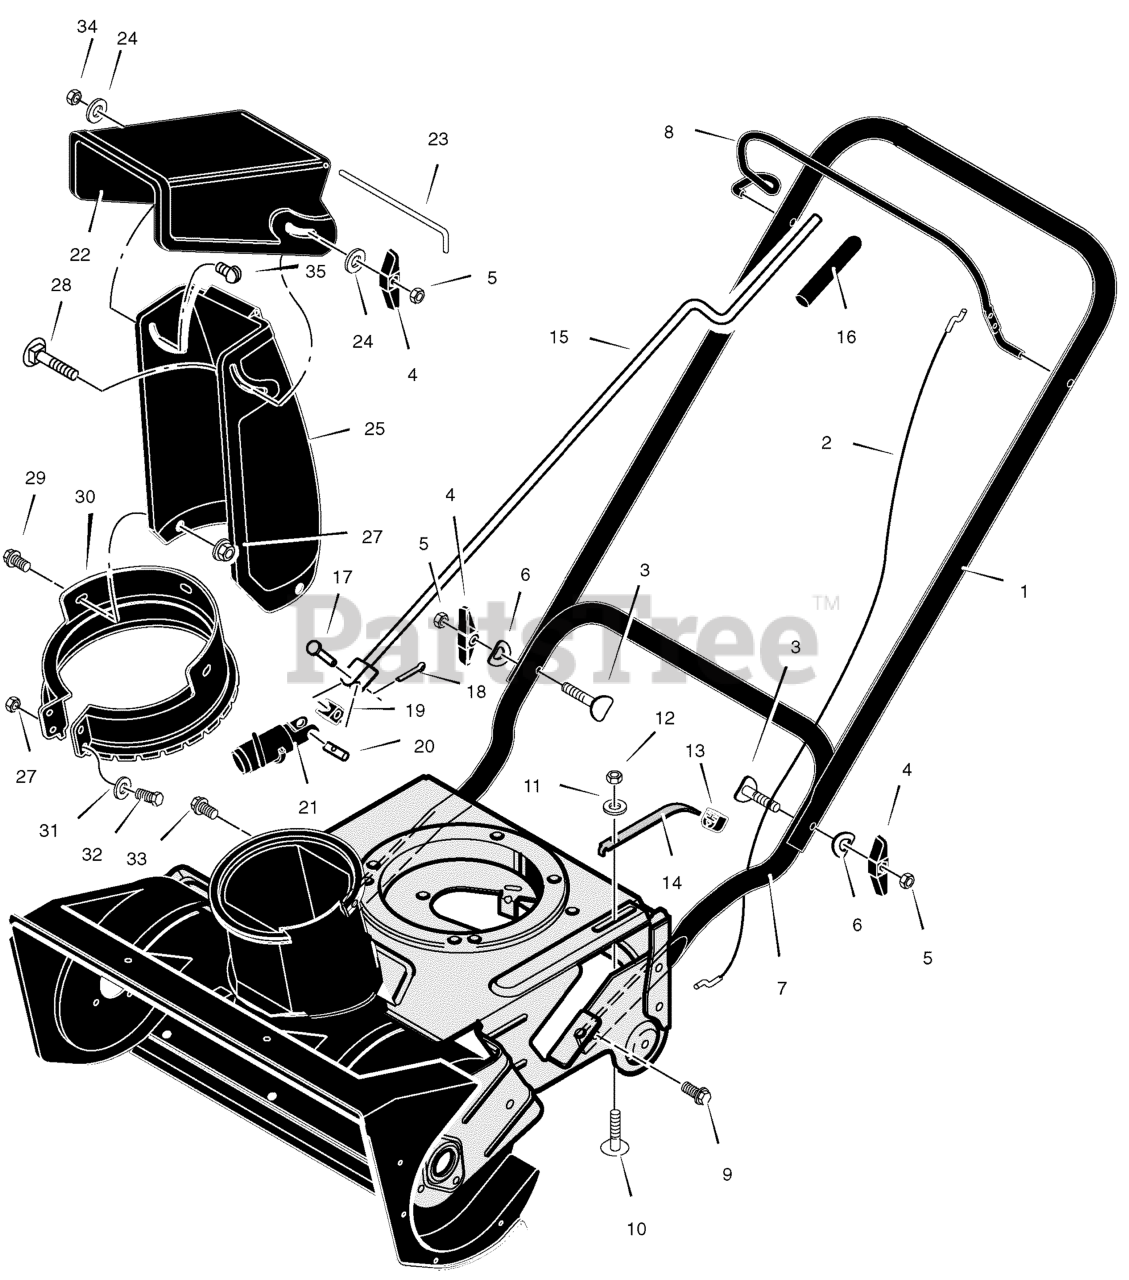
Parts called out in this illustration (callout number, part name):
1	Handle, Upper
2	Cable, Auger Drive
3	Bolt
4	Knob
5	Nut
6	Washer
7	Handle, Lower
8	Lever, Auger Drive
9	Screw
10	Bolt
11	Washer
13	Bushing, Tensioner
14	Bracket, Cable Tensioner
15	Rod, Crank
16	Grip, Crank Rod
17	Pin, Clevis
18	Pin, Cotter
19	Block, Universal Pivot
20	Pin
21	Gear, Worm
22	Deflector
23	Pin, Pivot
24	Washer
25	Chute, Discharge
27	Nut
28	Bolt
30	Ring, Chute
31	Washer
32	Bolt
34	Locknut
35	Bolt
